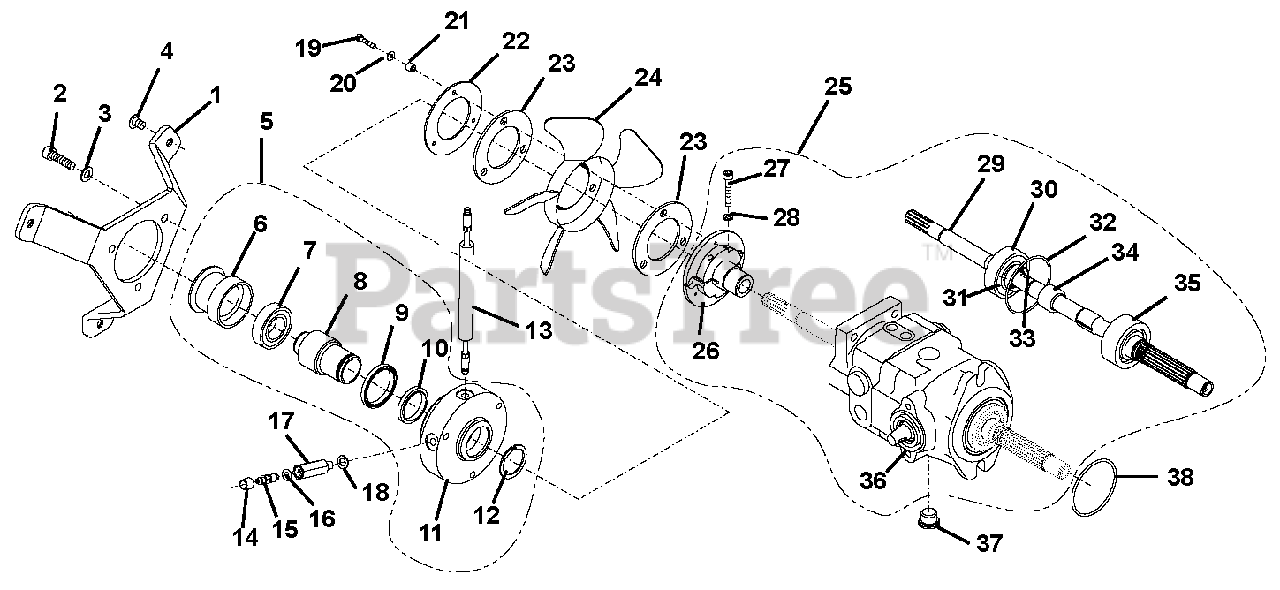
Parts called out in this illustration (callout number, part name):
2	Screw, M8 x 30
3	Washer
4	Bolt, M8 x 16
5	Cylinder Assembly (Includes 6 - 12)
6	Pressure Ring
7	Ball Bearing
9	Gasket, Piston
10	Gasket, Piston
11	Cylinder
13	Clutch, CPL Pipe
16	O-Ring, 6.00 x 3.00
18	Ring, Joint D7603A 8 x 14 CU
19	Screw, M4 x 20
20	Washer, FORM Metric 4.1/10.2 x 1.0
25	Hydraulic Pump
27	Bolt, Hex M6 x 8
28	Washer, Form Z 6.1/9.9 x 1.4
29	Drive Shaft
30	Ball Bearing
31	Oil Seal
32	O-Ring 62.00 x 2.00
34	Ball Bearing
35	Ball Bearing
36	Oil Seal
37	Plug, Drain
38	O-Ring, 60.00 x 2.50
